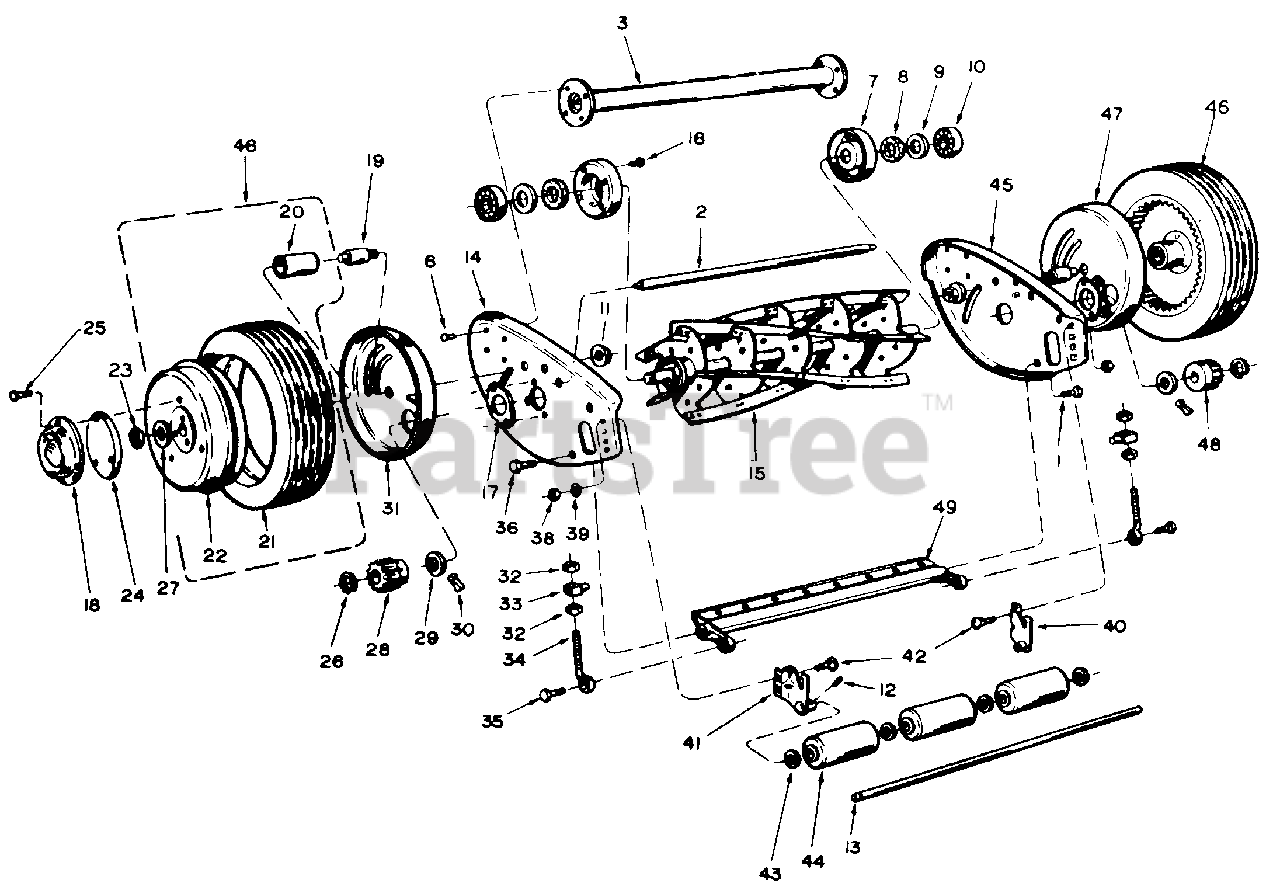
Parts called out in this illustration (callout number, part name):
1	Screw Front L.H. Thd.
2	Spacer End Plate
3	Spacer Tube Ass'y.
6	Rivet 3/16 x 3/8 Rd. Hd.*
7	Retai ner
8	Felt Washer
9	Felt Retainer
10	Bearing
11	Nut- Special
12	Roll Pin
13	R oll er Shaft
14	End Plate Trunnions - L.H.
15	Reel Ass'y. - 21 "
16	Rivet 3/16 x 13/32 Rd. Hd.*
17	Bearing Retainer
18	Hub Cap
20	Bearing
22	DriveWheel- LessTire
23	Retaining Ring
24	Wheel Weight
25	Scr. #10-32 x 1 3/ Thd. Cutting
26	Retaining Ring*
27	Washer
28	Pinion Gear- L.H.
29	Felt Washer
31	Gear Housing- L.H.
32	Hex Nut 3/8-24 Semi Fin*
33	Trunnion
34	Cutter Bar Adjusting Bolt
35	Screw- Rear
36	Screw- Front R.H. Thd.
38	Nut 5/8-18*
39	L. Wash. 5/16" I.D.*
40	Roller Brkt. - R.H.
41	Roller Brkt. - L.H.
42	Carr. Bolt 5/16-18 x 1*
43	Washer 1/2 x 1 1/16*
44	Roller - 3 Required
45	End Plate with Trunnions - R.H.
46	DriveWheel Ass'y. wire
47	Gear Housing- R.H.
48	Pinion Gear- R.H.
49	Cutter Bar Ass'y.
